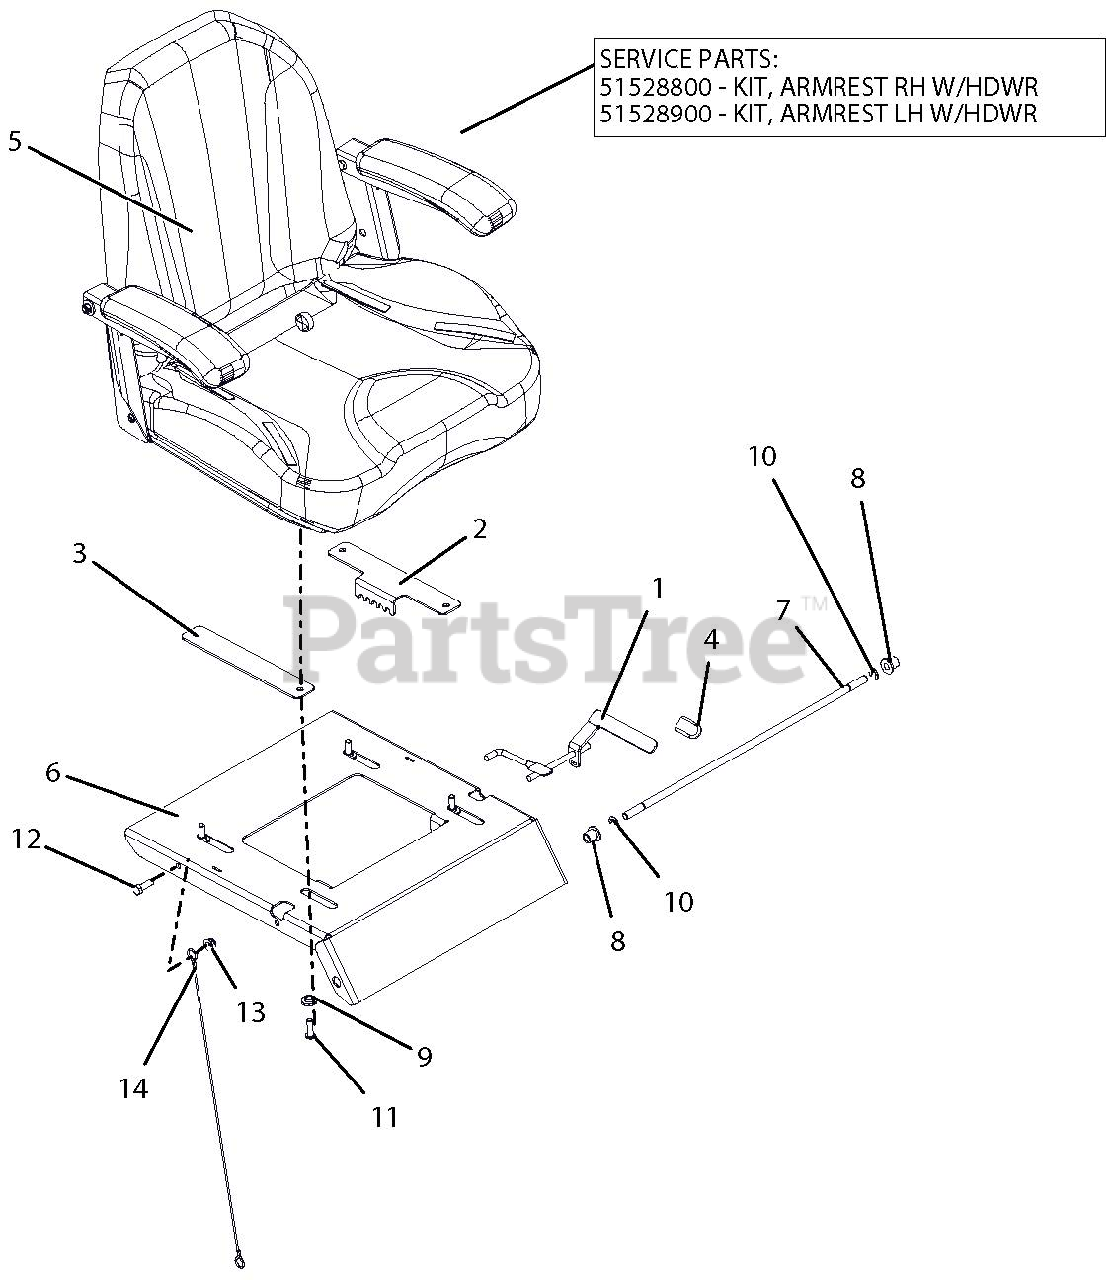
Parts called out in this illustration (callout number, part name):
1	WLDMT, ADJUSTABLE SEAT LATCH
2	PLATE, ADJUSTABLE SEAT TRACK
3	PLATE, ADJUSTABLE SEAT SLIDE
4	GRIP, SEAT LEVER, GREY
5	SEAT, MOWER
5	KIT, ARMREST LH
5	KIT, ARMREST RH
6	PLATE, SEAT
7	ROD, SEAT PIVOT
8	BSHG-FLG .38X.580X.667X.750
9	BSHG, FLG .325X.499X.26X.88
10	RG-RTNG-EXT .375X.035 TYP E
11	SCR-SKH .31-18X1.0 BTNHD YWZC
12	@BLT-HEX .31-18X1.00 GR5 YWZC
13	@NUT-LK-NYL-FLG .31-18 YWZC
14	LANYARD, SEAT CABLE .093X19.5
